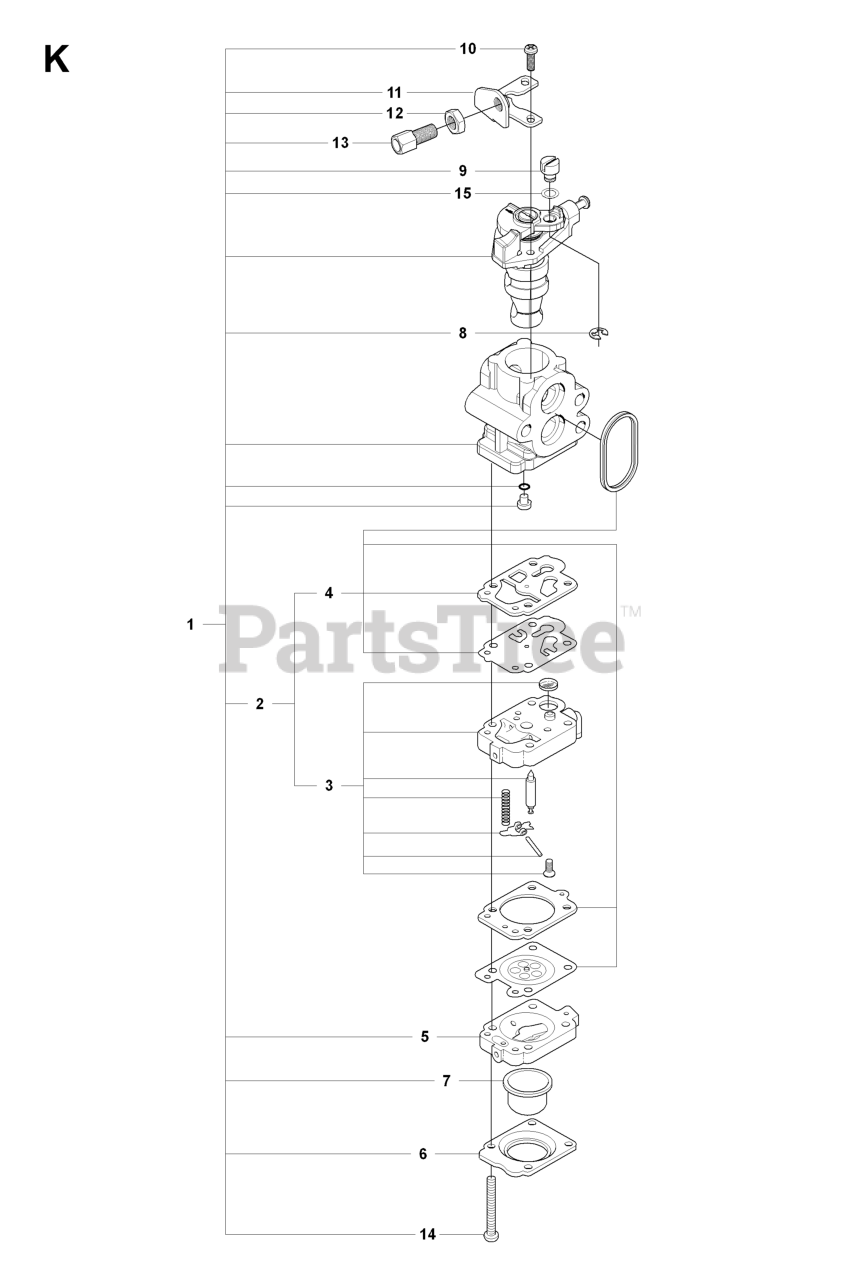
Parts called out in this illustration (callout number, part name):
1	CARBURETOR ASSY
2	REBUILD KIT
4	GASKET KIT
5	BODY
7	PUMP
12	NUT
13	SCREW
